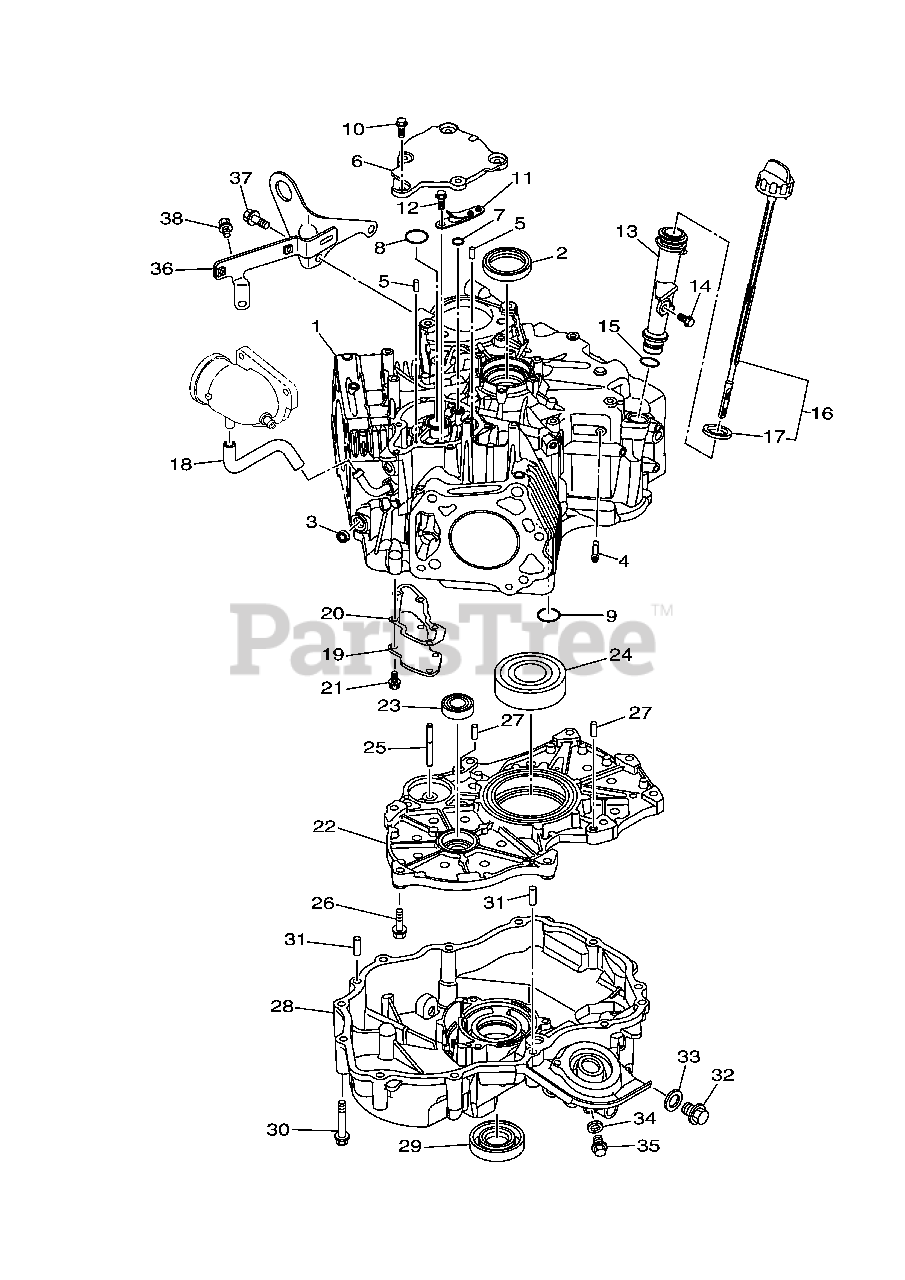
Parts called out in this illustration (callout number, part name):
1	CRANKCASE ASSY 1
2	OIL SEAL
3	OIL SEAL
4	PIPE, JOINT
6	COVER, AIR CLEANER
10	BOLT, FLANGE
11	REED VALVE ASSY
12	BOLT, FLANGE
13	PIPE, OIL
14	BOLT, FLANGE
16	GAUGE, LEVEL
18	HOSE, BREATHER 1
20	GASKET, BREATHER
21	BOLT, FLANGE
22	COVER, CRANKCASE 1
25	SHAFT, FLYWEIGHT
26	BOLT, FLANGE
27	PIN, DOWEL
28	COVER, CRANKCASE 2
29	OIL SEAL
30	BOLT, FLANGE
31	PIN, DOWEL
32	PLUG, STRAIGHT SCREW
35	BOLT, FLANGE
36	HANGER, ENGINE 2
37	BOLT, FLANGE
38	BOLT, FLANGE
